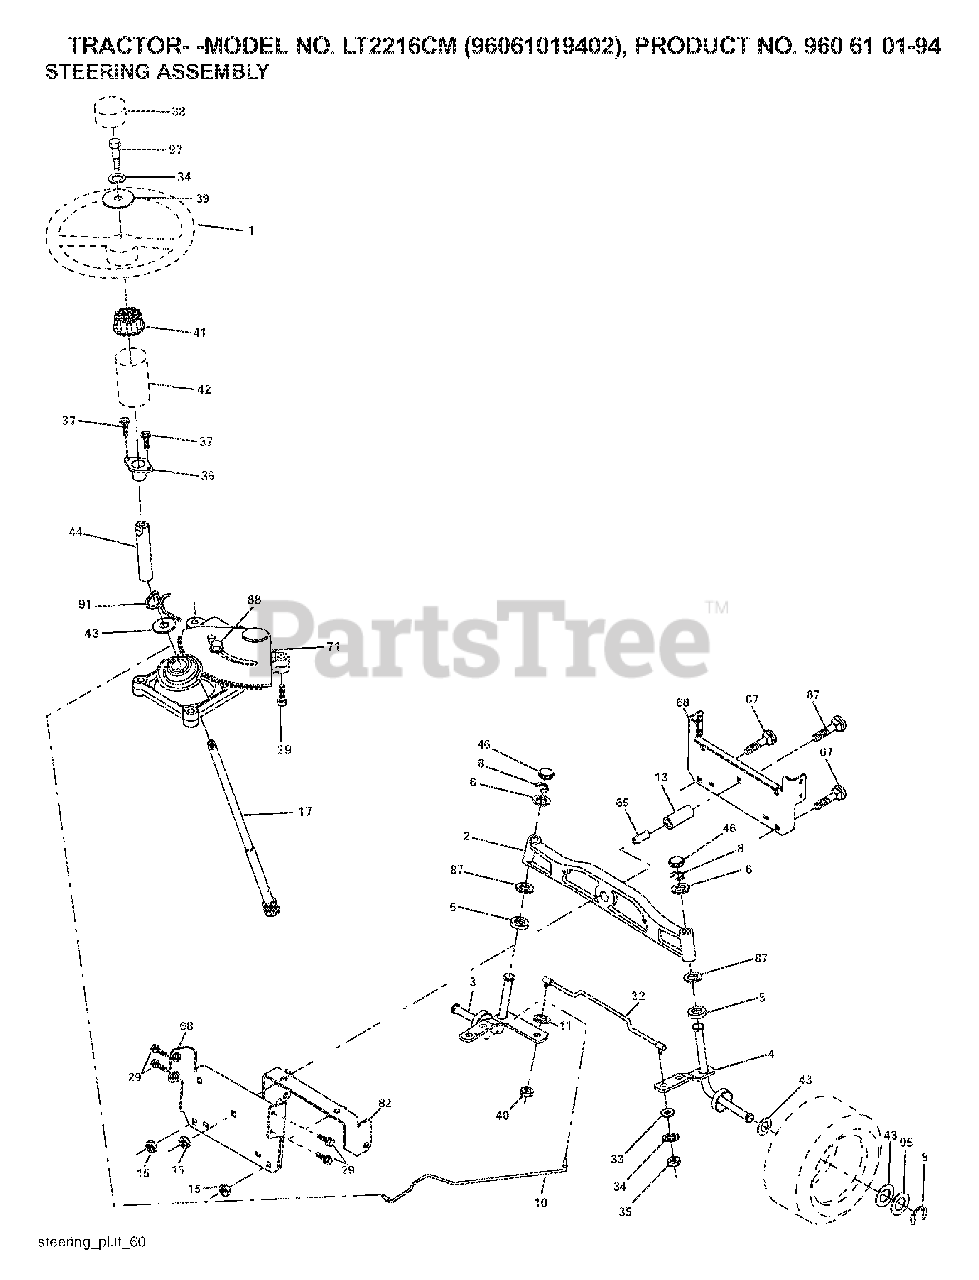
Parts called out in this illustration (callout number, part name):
1	WHEEL.STEERING.PREM.2.BLK
2	AXLE ASSY FRONT
3	SPINDLE.ASM.LH.15"TIRES
4	SPINDLE.ASM.RH.15"TIRES
8	RING CLIP
10	DRAGLINK.15".TIRES.2001
11	WASHER, LOCK 3/8
13	TUBE, PIVOT AXLE
15	NUT
17	SHAFT STEERING SPLINE
29	SCREW, 3/8-16X3/4
32	ROD.ASM.TIE.BALL.JOINT.NOVAN
33	WASHER M
34	LOCKWASHER
35	NUT, CROWNLOCK
36	BUSHING, STEERING
38	INSERT.CAP.STRG.WH.BLACK
39	WASHER.11/32
40	NUT CROWNLOCK 3/8-24
41	ADAPTER, WHEEL STNG..
42	BOOT.STEERING.SHAFT.BLACK
44	SHAFT.EXTEN.STRG.SPLINE
46	CAP.SPINDLE
65	SPACER BRACE AXLE
67	BOLT CARRIAGE
68	BRACE.AXLE.15"TIRES
71	STEERING ASM
82	BRACKET.SUSP.CHASSIS.FRONT.15
87	WASHER, FLAT .781 X 1 1/2"
88	BOLT, SHOULDER 7/16-20
91	CLIP.STEERING
95	WASHER.HARDENED
